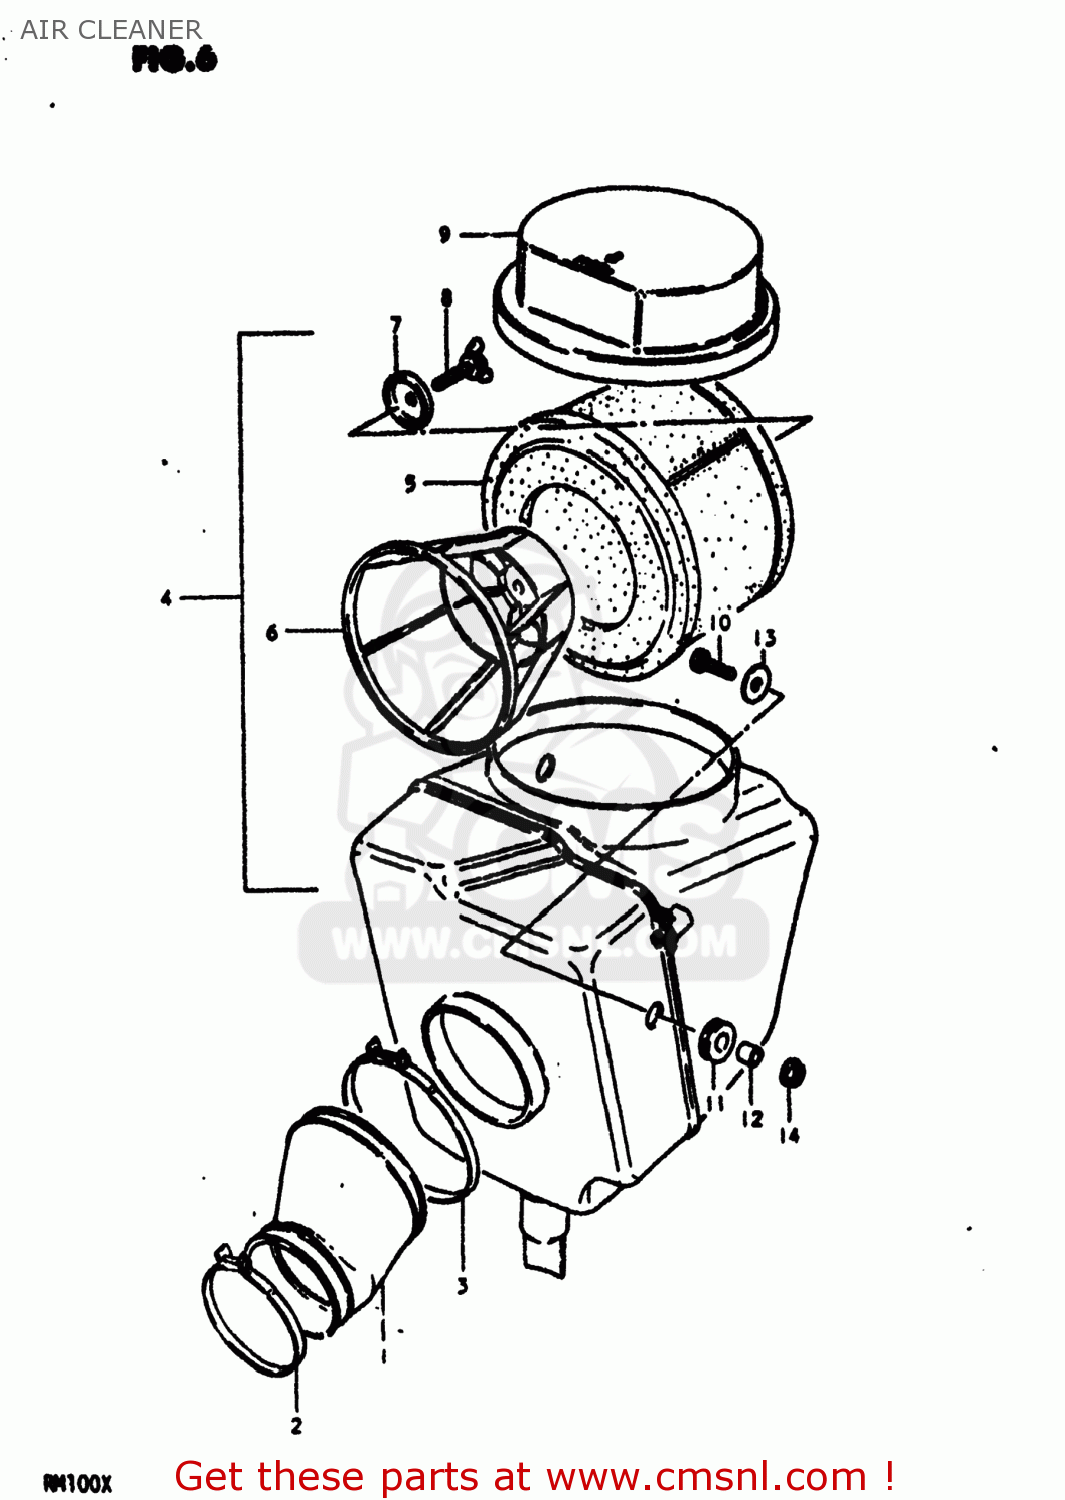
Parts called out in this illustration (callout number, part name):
1	TUBE,AIR CLEANER OUTLET
2	CLAMP
3	CLAMP
4	CLEANER ASSEMBLY,AIR
5	FILTER
6	HOLDER
7	HOLDER,FILTER
8	WING BOLT,AIR CLEANER
9	CAP,AIR CLEANER
10	BOLT
11	CUSHION
12	SPACER (6.1X9X9)
13	WASHER (6.5X20X1.2)
14	NUT
